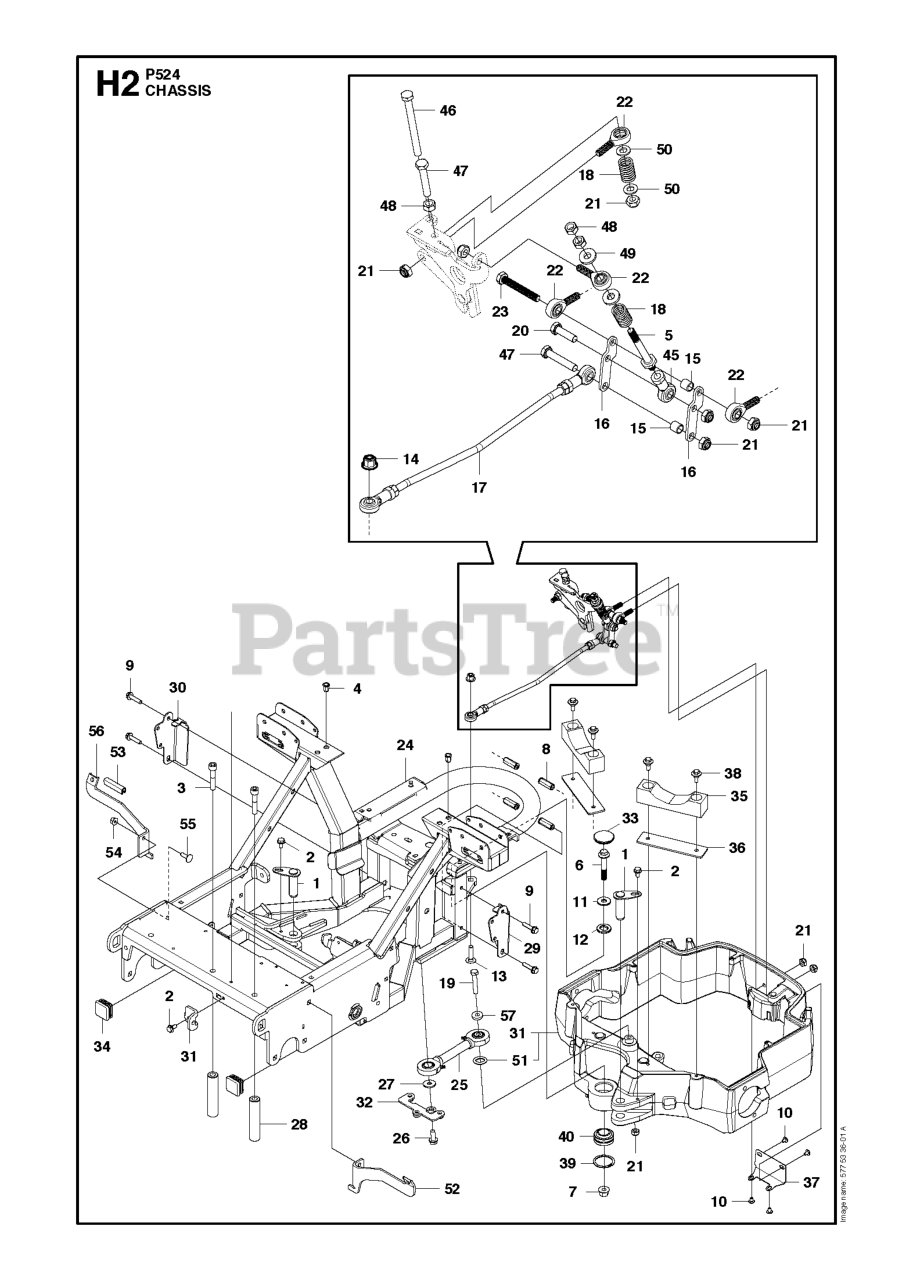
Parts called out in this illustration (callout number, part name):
33	HUB CAP PIVOT WHEEL
38	COLLAR SCREW
48	Nut
50	WASHER
54	NUT FLANGE
